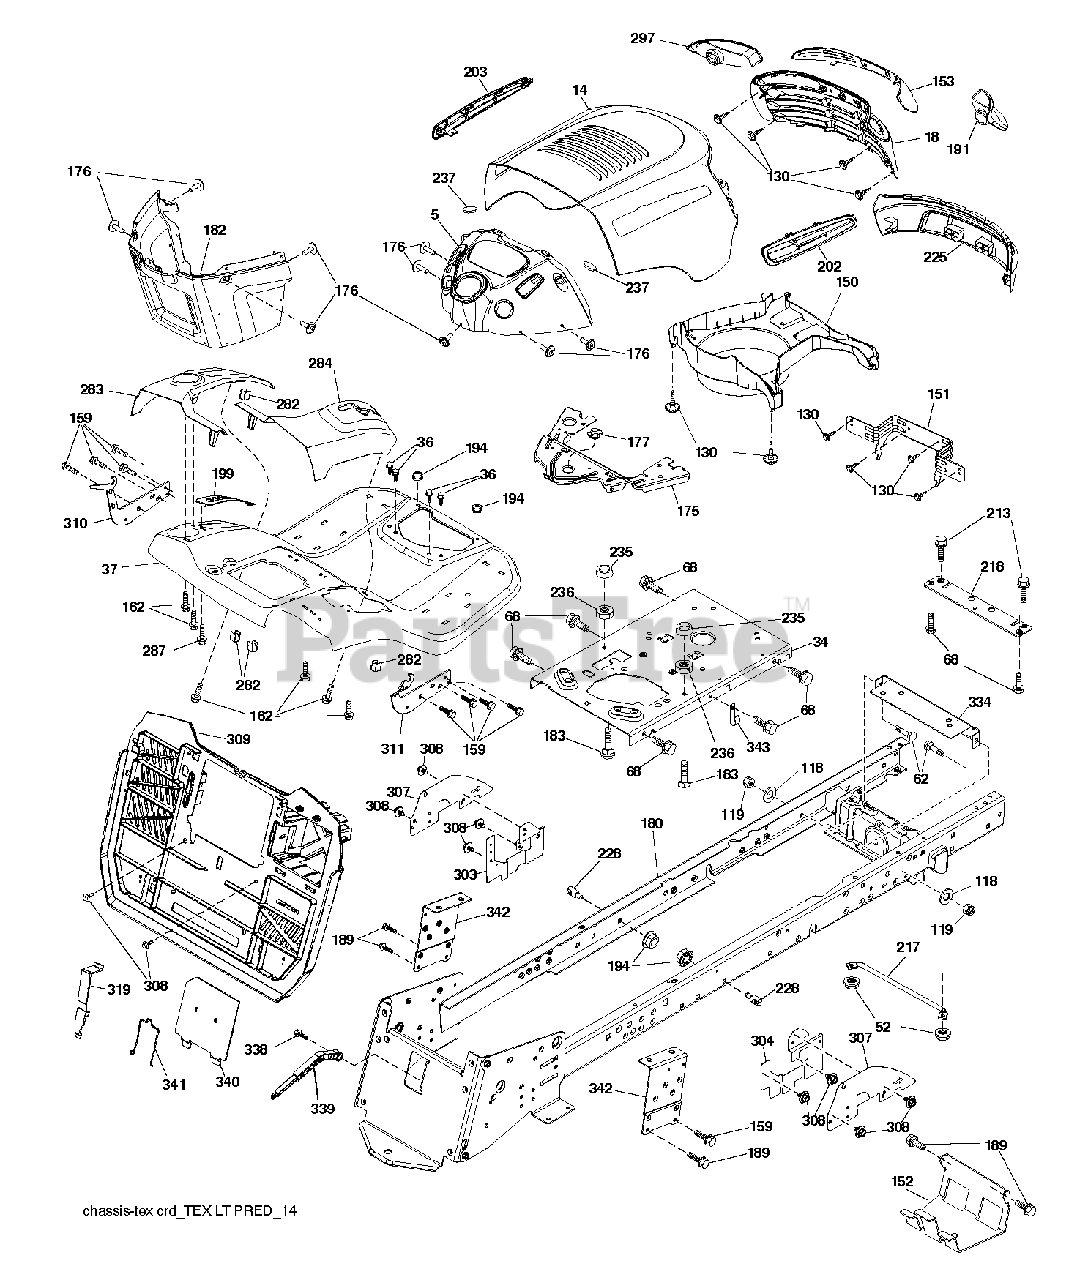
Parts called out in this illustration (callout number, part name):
36	SCREW 5/16"
52	LOCKNUT
119	LOCKNUT
130	SCREW.#10 X 0.750.BOS THREAD
151	BRACKET.PIVOT.ALPHA.LT
152	SHIELD BROWNING
153	LENS.PREDATOR.LT
159	SCREW, 3/8-16X3/4
162	SCREW.HI-LO.CONSOLE
175	CROSSMEMBER
176	SCREW.#10-24X5/8.RN.QU
177	BUSHING STEERING
182	DASH.LWER.PREDATOR/HUSQ.LT
183	BOLT.5/16-18X1-1/4 FULL THD
189	SCREW
191	INSERT.REFLECT.PREDATOR.LT.RH
194	NUT LOCK HEX FLANGE 5/16-18
213	BOLT
217	ROD.PIVOT.HOOD
218	X-PIECE.HOOD.STOP.NON/
228	STUD.FASTNER.W/ANTI-ROTATE
235	SPACER FENDER
236	NUT.CENTERLOCK.5/16-
237	PLUG.MOUNT.CARGO.BLK
282	CLIP.RETAINER.CONSOLE.LT.HUSQ
297	REFLECTOR.INSERT.PRED.LH.LT
303	SHIELD.LWR.LH.LT.30DECK.CRDSRD
308	BOLT, 5/16-18 X 1 3/4
